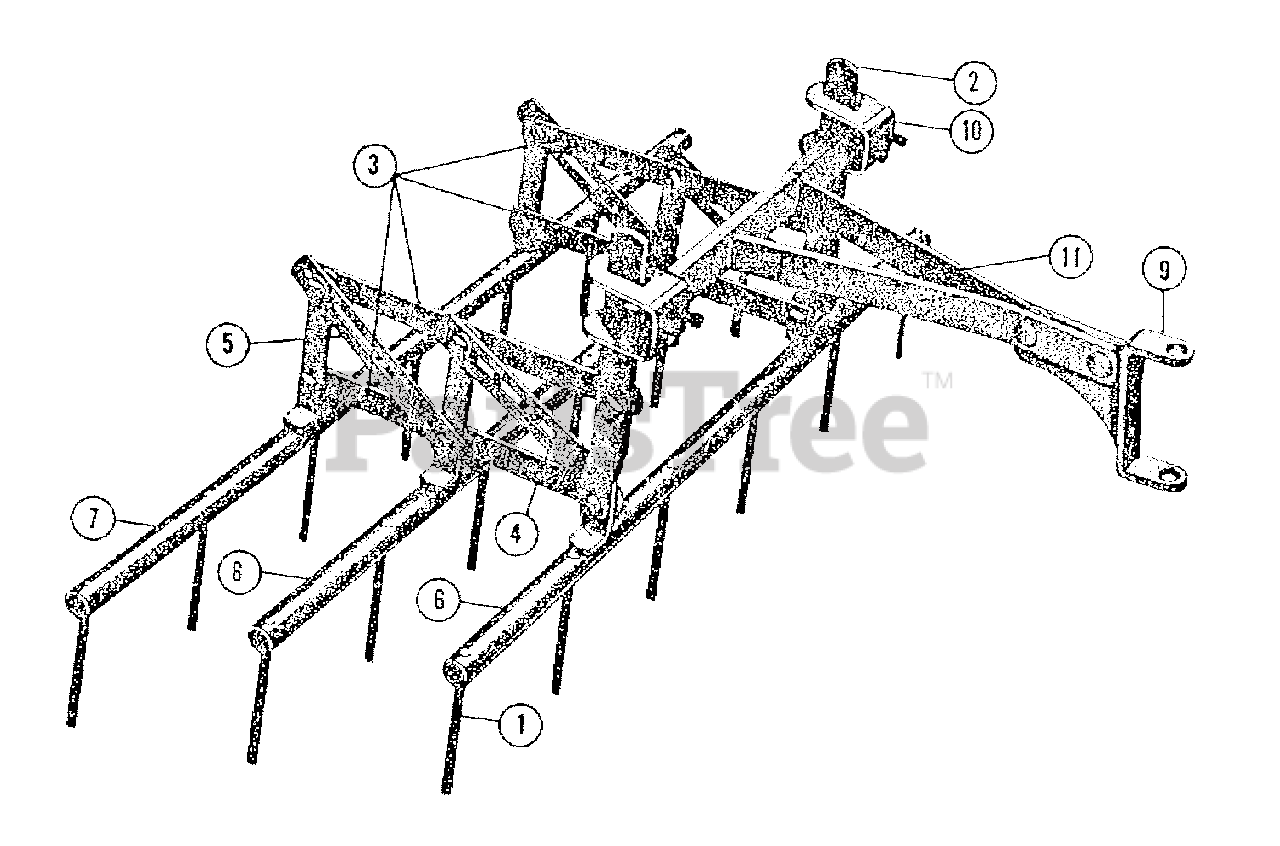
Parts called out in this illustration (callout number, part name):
2	STANDARD
3	PARALLEL BAR
4	TILT ADJUSTMENT BAR
5	TOOTH ADJUSTMENT BAR
6	FRONT PIPE ASSEMBLY
7	REAR PIPE ASSEMBLY
8	CENTER PIPE ASSEMBLY
9	DRAW BAR END
10	SHANK CLAMP
11	DRAW BAR ASSEMBLY
